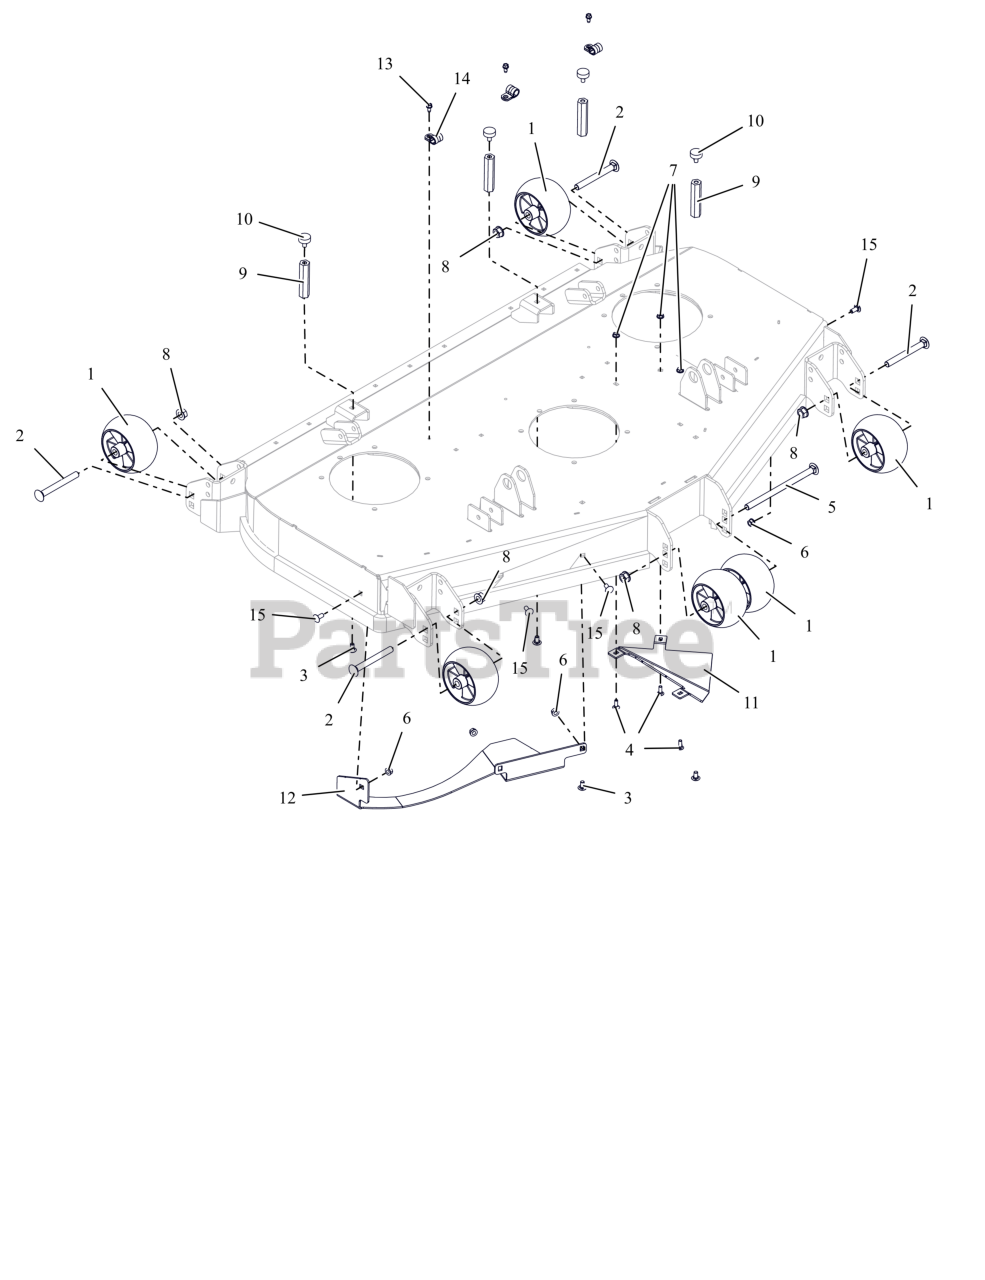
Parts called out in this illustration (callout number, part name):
1	WHEEL, ANTI SCALP - 5X3 CTR W/RIBS
2	BLT-RHNS .50-13X4.50 G5 ZCC NS
3	BLT,RHSSN.31-18X.625 G5 ZCCP30
4	BLT, RHSN .25-20X.750 G5 ZCC
5	BLT-RHSN .50-13X8.00 G5 ZCC NS
6	NUT,LK-CTR-FLG .31-18 GF ZCC
7	NUT-LK-CTR-FLG .25-20 ZC120
8	NUT-LK-CTR-FLG .500-13 GG ZCC
9	NUT, COUPLING .312-18 X 3.375
10	BUMPER, RUBBER
11	BAFFLE, 52" TRIANGLULAR INSERT (ORANGE)
12	DEFLECTOR, 52" BOLT-IN BAFFLE (ORANGE)
13	SCR-TAP .25-20X.50 HWH ZCC
14	CLAMP, CUSHIONED STEEL
15	BLT, RHSSN.31-18X.750 G5 ZCC
